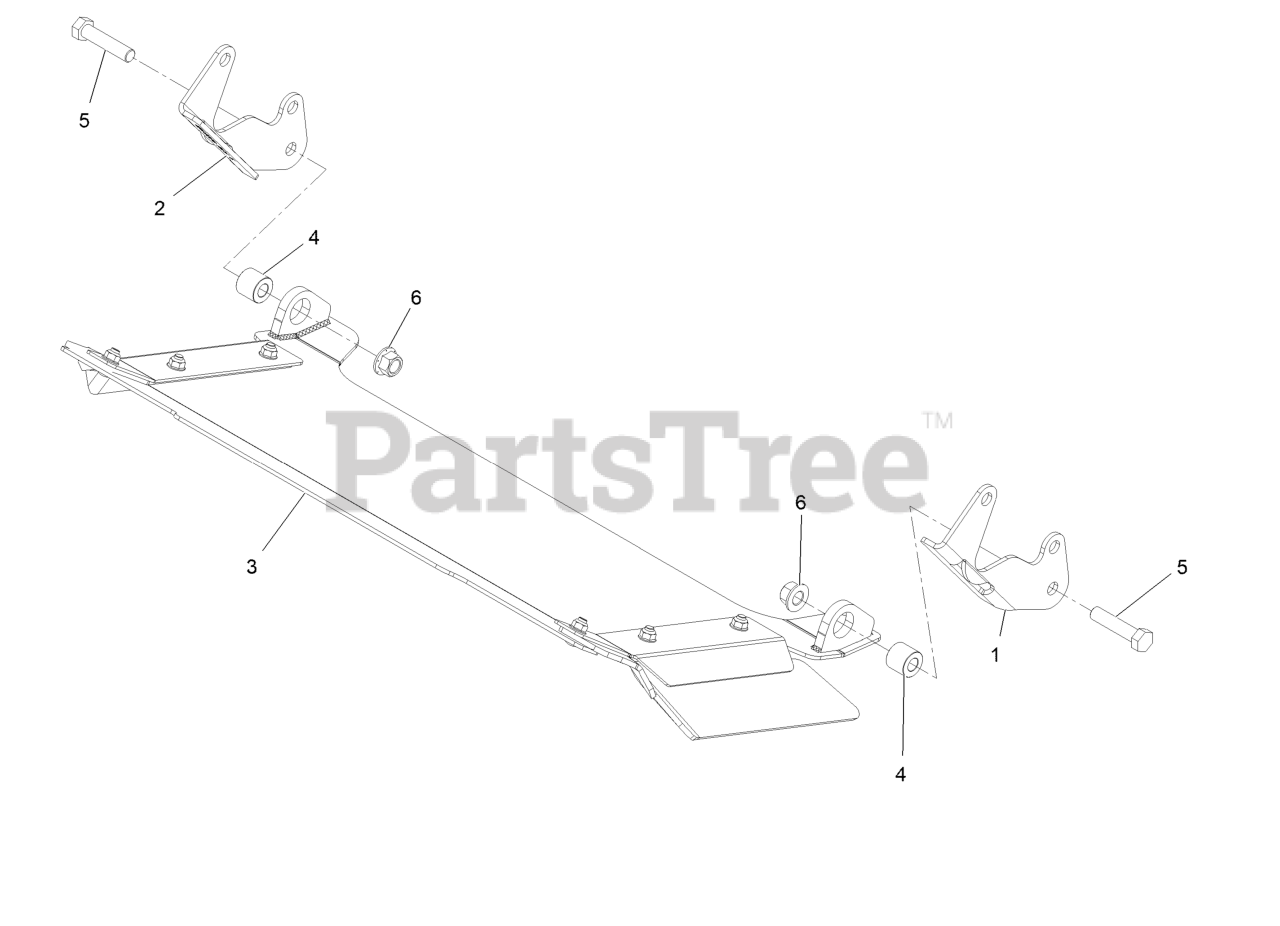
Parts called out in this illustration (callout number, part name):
1	Bracket-Discharge Mount, LH
2	Bracket-Discharge Mount, RH
3	Discharge Tunnel ASM
4	Bushing-Sleeve
5	Screw-HH 1/2-13 X 2 1/4
6	Nut-Lock 1/2-13
